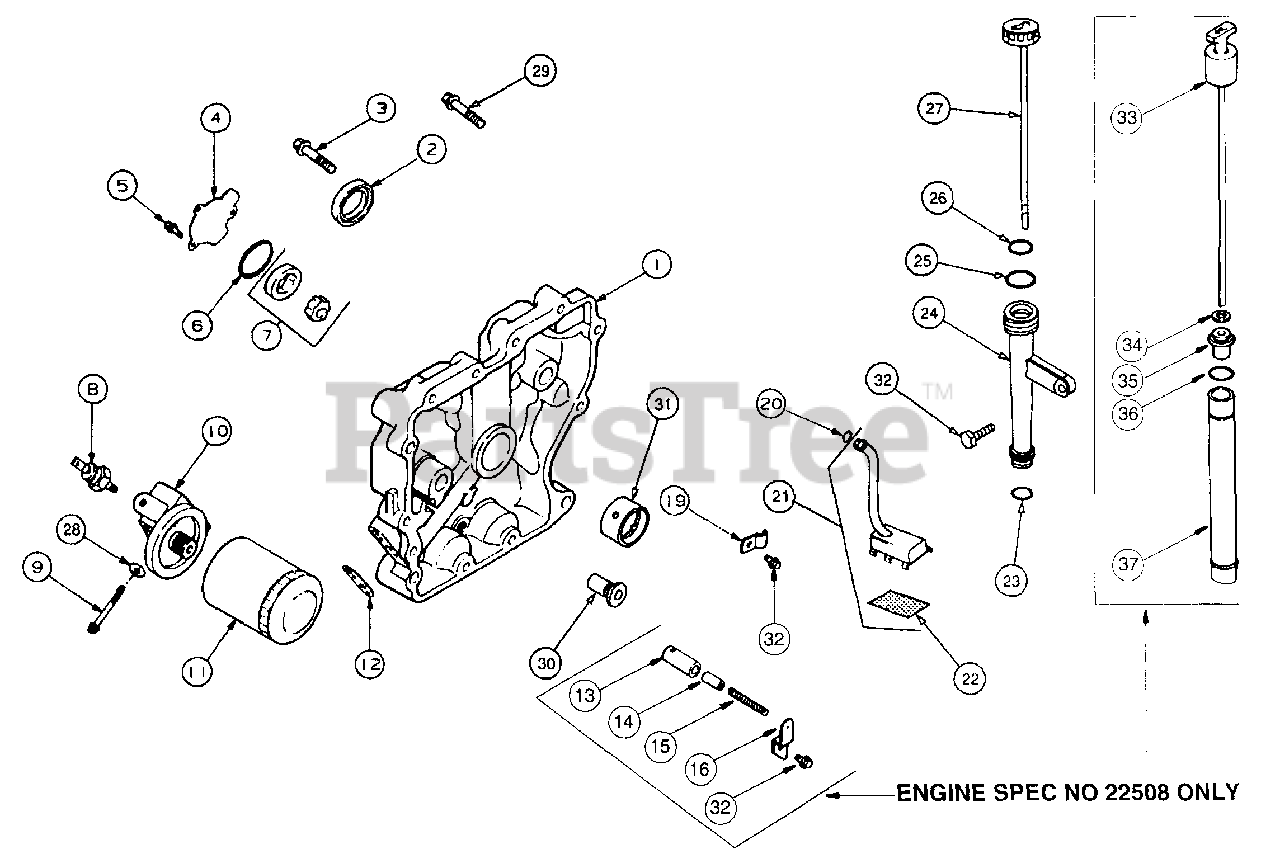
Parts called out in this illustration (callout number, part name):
1	Plate Assembly, Closure
2	Seal, Oil (PTO End)
3	Screw, Closure Plate, M8 x 1.25 x 45
4	Cover, Oil Pump
5	Screw, Oil Pump Cover, M5 x .8 x 16
6	O-Ring, Oil Pump
7	Pump Assembly, Oil
8	Switch, Oil Pressure
9	Screw, Oil Filter Adapt, M6 x 1 x 55
10	Adapter, Oil Filter
11	Filter, Oil
12	Gasket, Oil Filter Adapter
13	Body, Oil Pump Relief Valve
14	Piston, Oil Pump Relief Valve
15	Spring, Oil Pump Relief Valve
16	Bracket, Oil Pump Relief Valve
19	Clip Oil Tube
20	O-Ring, Oil Pick-Up
21	Kit, Oil Pick-Up
22	Pick-up, Oil Screen
23	O-Ring, Lower Oil Fill Tube
24	Tube, Oil Fill
25	O-Ring, Upper Oil Fill Tube
26	O-Ring, Dipstick Cap
27	Cap/Dipstick, Oil Fill
28	Washer, Plain, 1/4
29	Screw, Hex Flange M8 x 1.25 x 45
30	Valve, Oil Pressure Relief
31	Bearing, Thrust
32	Screw, Hex Flange M5 x .8 x 16 1
33	Dipstick Assembly
34	Washer, Plain, 5/16
35	Seal, Rubber
36	O-Ring, Lower Oil Fill Tube
37	Tube Oil Fill
